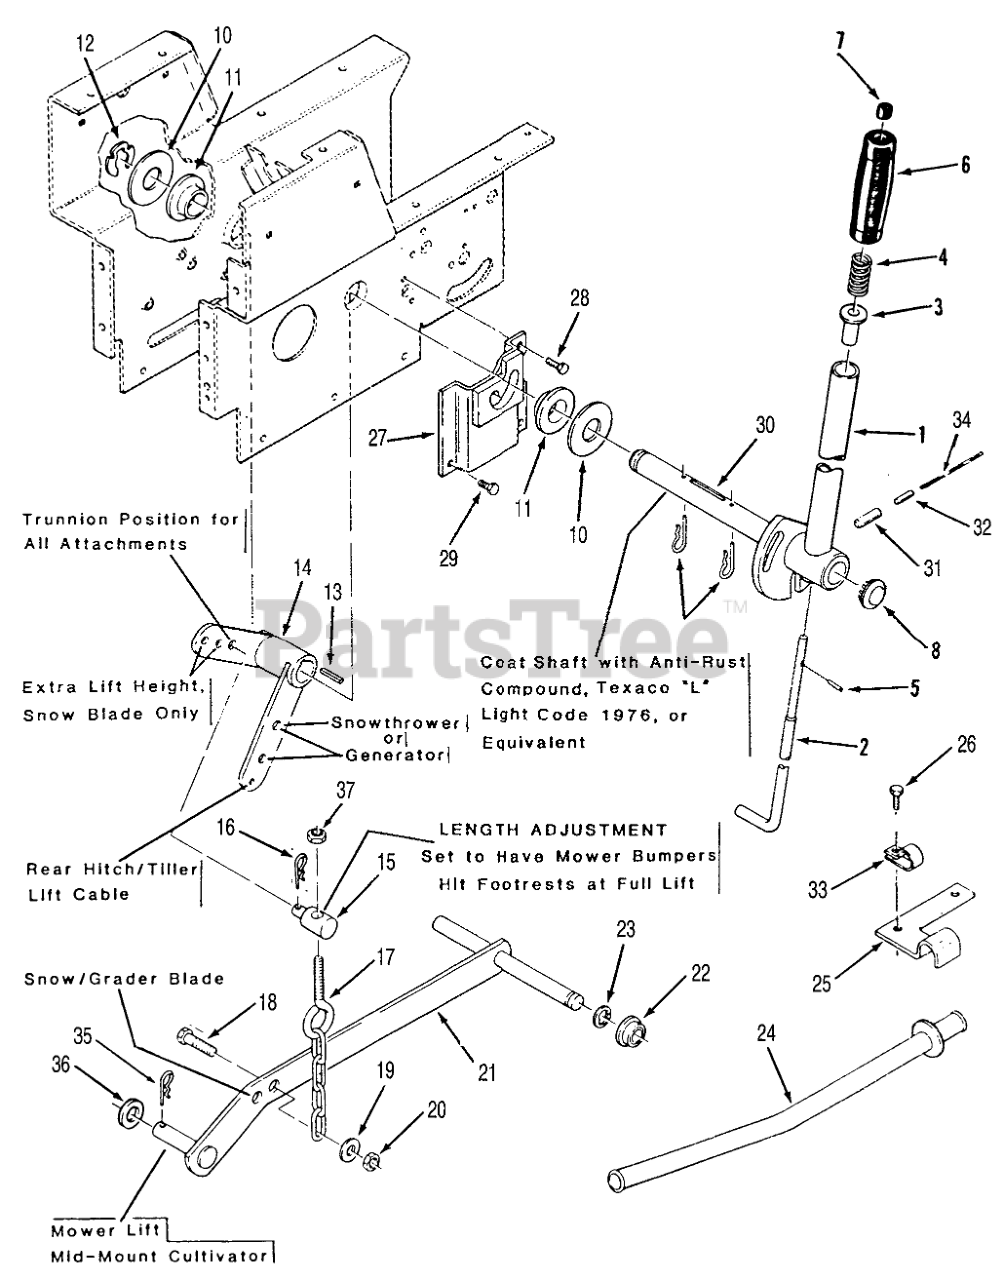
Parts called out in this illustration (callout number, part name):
1	Lift Lever (Includes Items 46, 47, 48)
2	ROD-LATCH LIFT
3	RETAINER-SPRING
4	SPRING-COMPRESSION
5	PIN-SPIROL
6	HANDGRIP
7	CAP-ROD, PLUNGER
8	PLUG
9	Pin-Cotter
10	WASHER
11	BEARING-FLANGE
12	Retainer
13	KEY-SQUARE
14	Bellcrank
15	TRUNNION-LIFT
16	Hairpin
17	CHAIN-LIFT
18	Bolt
19	WASHER 5/16 SAE
20	Nut
21	Bar-Lift
22	BUSHING
23	E Ring
24	TUBE ASSY COMPLET R
25	CLAMP-CONDUIT R
26	BOLT
27	Latch Bracket
28	SCREW
29	Bolt
30	SHAFT-LIFT LEVER
31	SPIROL PIN
32	Roll Pin
33	CLIP
34	Lock Wire
35	Hairpin Cotter
36	Washer
37	NUT
